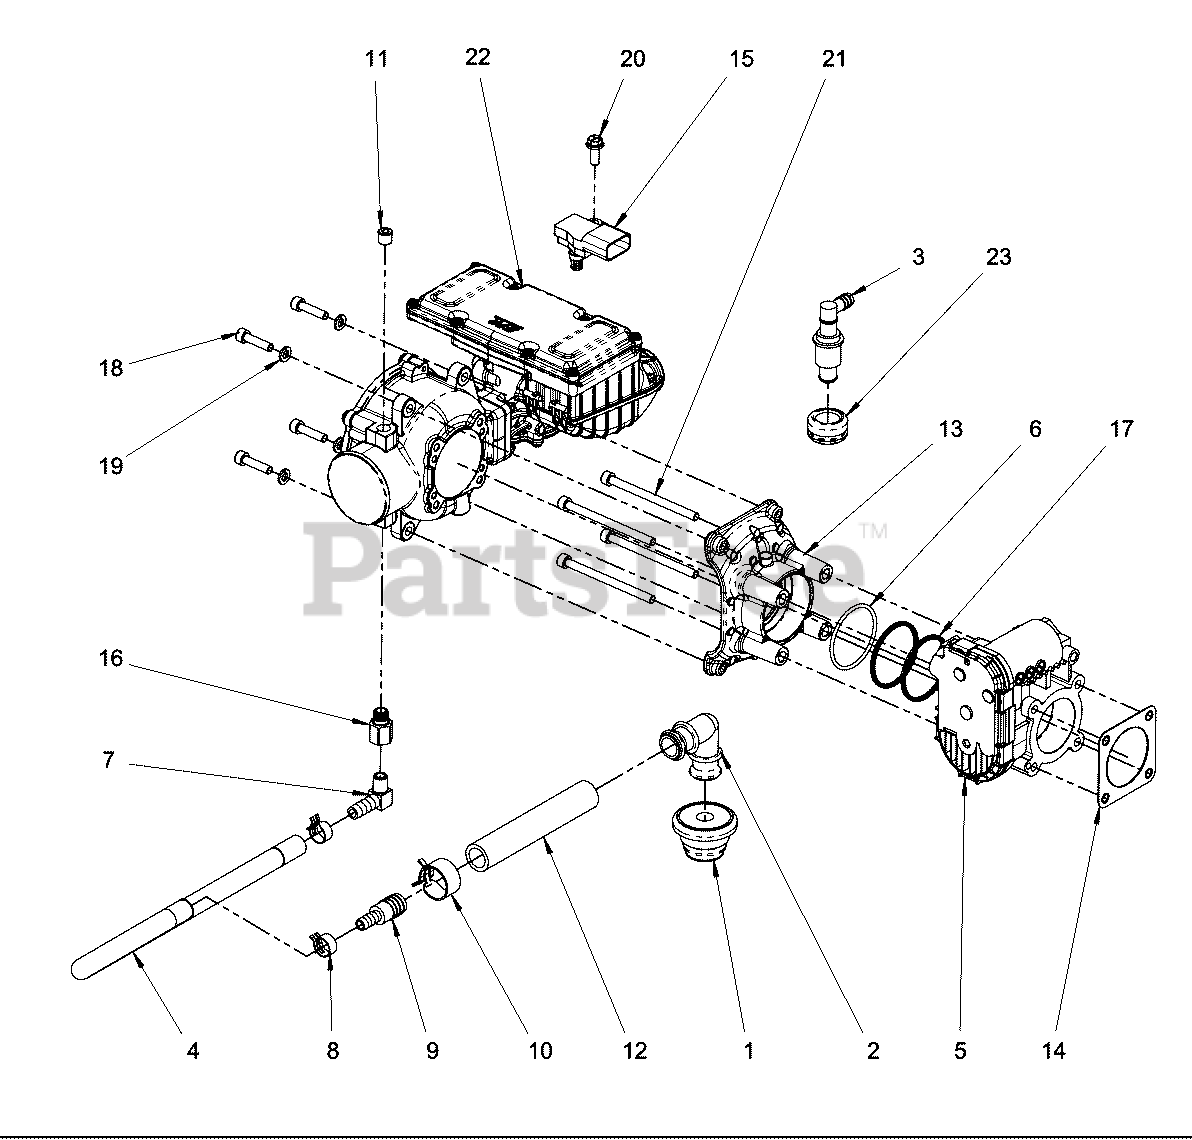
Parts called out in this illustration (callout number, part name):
4	* HOSE
5	THROTTLE BODY
8	* CLAMP
10	* CLAMP
11	* PLUG
12	* HOSE
18	* BOLT
19	WASHER
20	* BOLT
21	* BOLT
22	PROGRAMMED EPR
23	GROMMET
